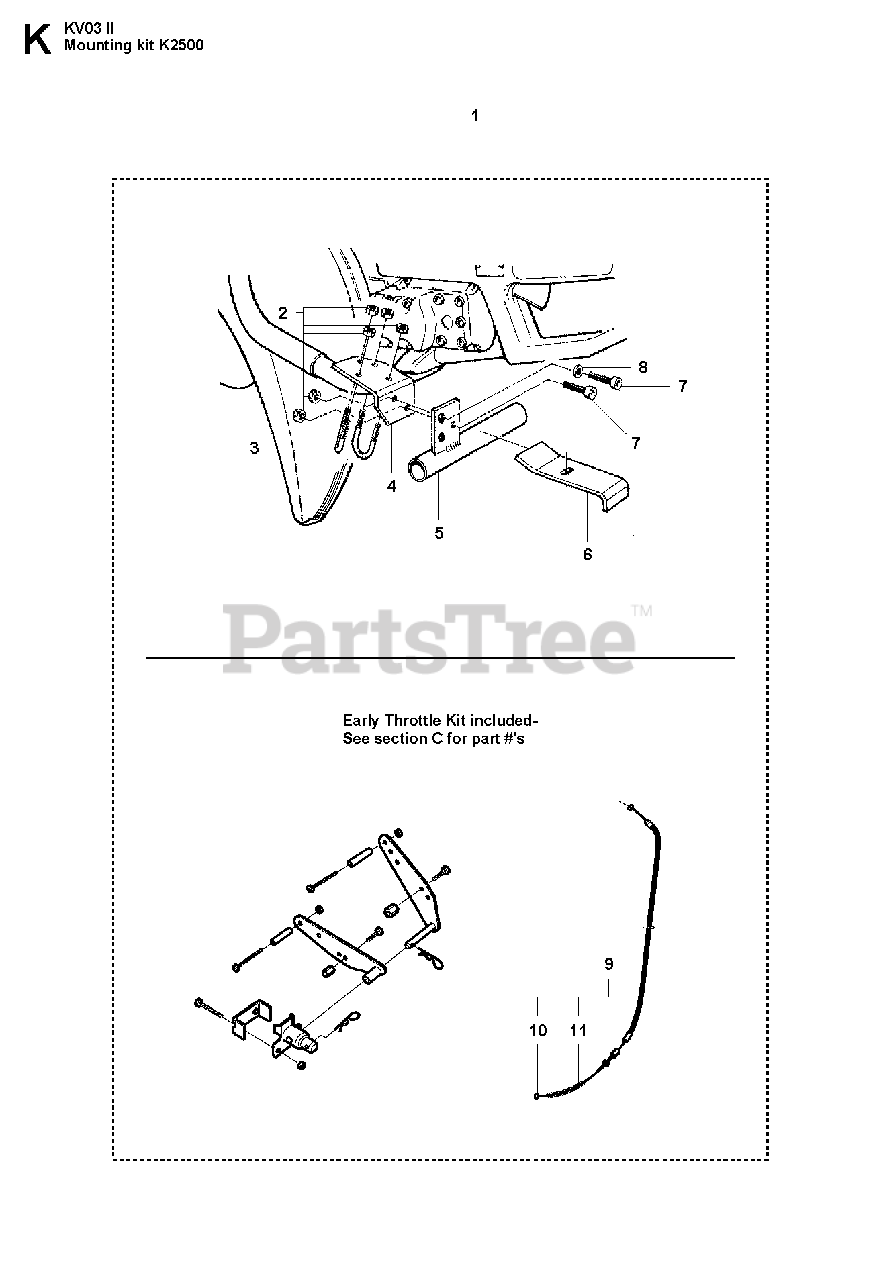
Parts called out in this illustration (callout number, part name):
1	CUTTING TROLLEYIncl. 2 - 9
6	PRESSURE PLATE
9	THROTTLE WIREIncl. 10, 11
